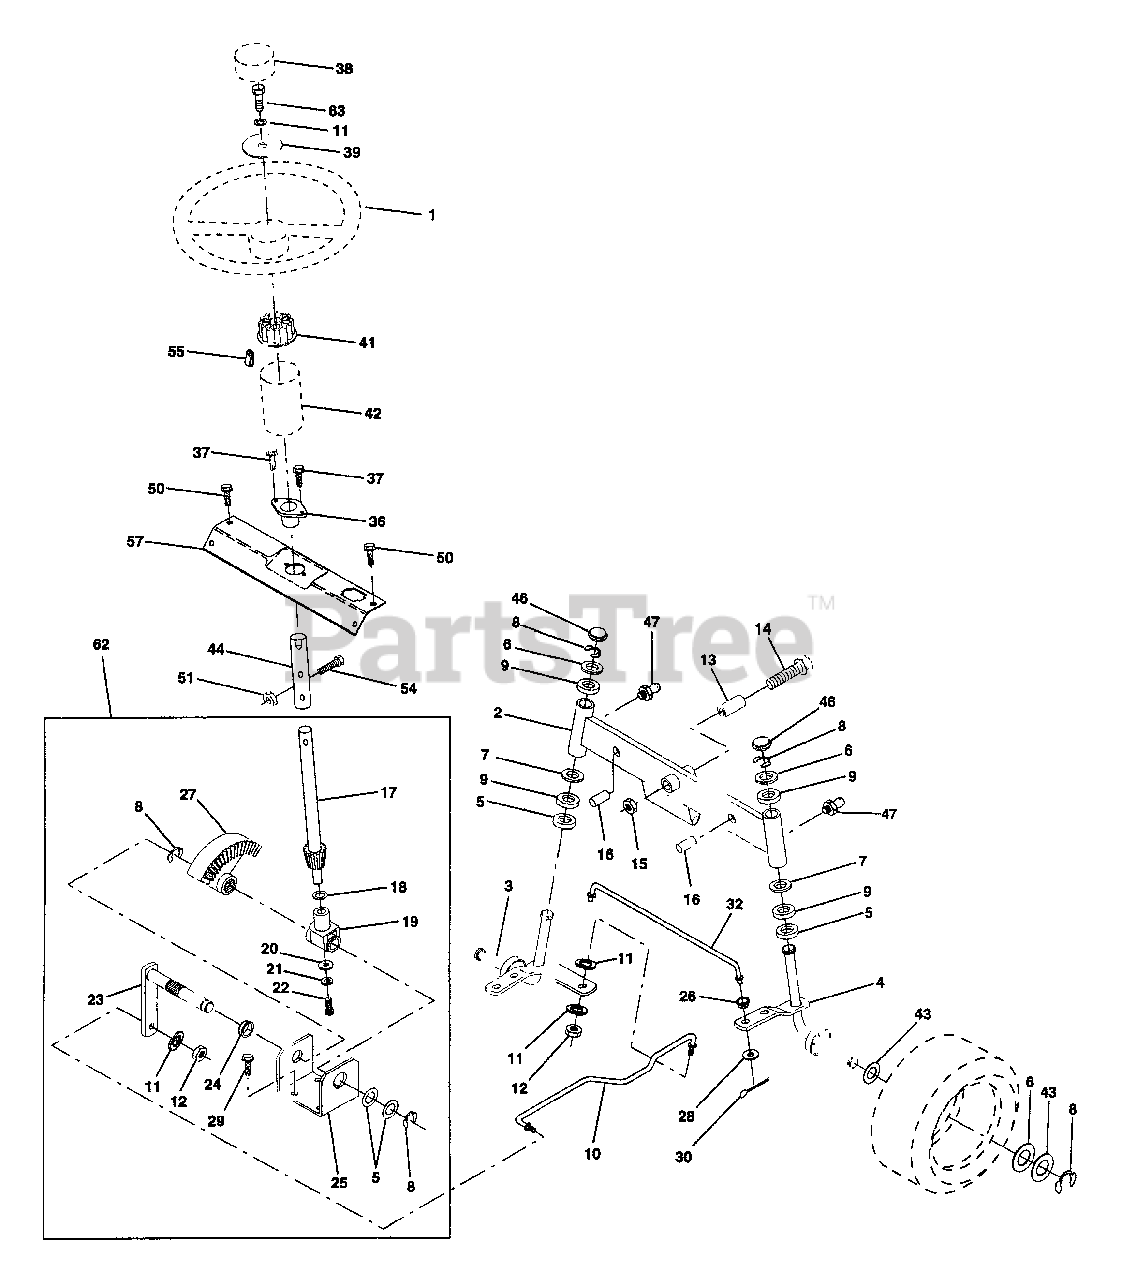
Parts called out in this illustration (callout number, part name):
1	Wheel Steering Auto Grey
2	Axle Asm Fr LT W/gzks 38/42
3	Spindle Asm LH
4	Spindle Asm RH
5	Bearing Race Thrust Harden
6	Washer 25/32 X 1-5/8 X 16 Ga
7	Washer 27/32 X 1-1/4 X 16 Ga
8	Ring Klip M5304-75
9	Bearing Col Strg Blk
10	Link Drag Sol Ball Jt 20 064
11	Washer Lock Hvy Hlcl Spr 3/8
12	Nut Fin Hex 3/8-24 Unf
13	Spacer Bearing Axle Front
14	Bolt Hex 5/8-11 Unc X 3-1/2
15	Nut Lock Flange 5/8-11 Unc
16	Pin Axle 5/8 X 1 55/1 54 Lg
17	Shaft Asm Strg Private Label
18	Washer Thrust 515x 750x 033
19	Support Shaft
20	Washer Shim 1/4 X 5/8 X 062
21	Washer Lock Hvy Helical 1/4
22	Screw Cap Socket Head Phos & Oil
23	Shaft Asm Pittman
24	Nyliner Snap In
25	Bracket Steering
26	Bushing Link Drag Blk LR
27	Gear Sector
28	Washer 13/32 X 7/8 X 16 Ga
29	Screw Thdrol 3/8-16x3/4 Ty-tt
30	Pin Cotter 1/8 X 3/4 Cad
32	Rod Tie Wire Form 19 75 Mech
36	Bushing Strg
37	Screw TT #10-32.5.3/8 Flange
38	Insert Cap Strg Wh Au
39	Washer 13/32 X 2-3/8 X 8 Ga
41	Adaptor Wheel Strg .758/.753 ID
42	Boot Steering Shaft
43	Washer 25/32 X 1 1/4 X 16 Ga
44	Extension Steering
46	Cap Spindle Fr Top Blk
47	Fitting Grease
50	Screw Hex Wsh Thdrol 1/4-20 x 3/4
51	Nut Lock Hex w/Ins 5/16-18
54	Bolt Fin Hex 5/16-18 Unc x 1-1/4
55	Clip Tinnerman
57	Support Shaft Steering
62	Kit, Steering Assembly
63	Bolt, Fin, Hex 3/8-16 unc X 1 Gr. 5
